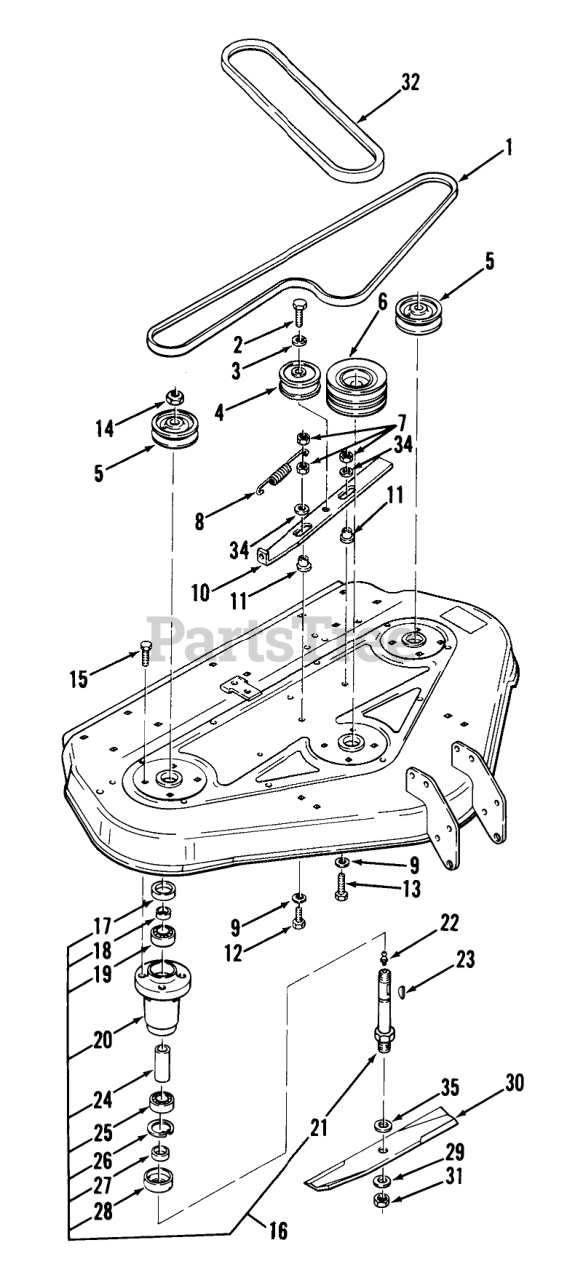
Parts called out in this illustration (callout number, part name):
1	V-BELT
5	PULLEY-BLADE DRIVE
6	PULLEY-MOWER
8	SPRING-EXTENSION
9	WASHER
10	BAR-IDLER SUPPORT
11	SPACER-BUSHING
18	SPACER-SEAL
19	BEARING-BALL
20	HOUSING-SPINDLE
21	SPINDLE SHAFT ASM
23	Hi-Pro Key 3/16 x 5/8
25	BEARING-BALL
26	Ring-Snap
27	SPACER-BLADE
29	SpeciaI Washer
30	S/A BLADE KIT
34	WASHER
